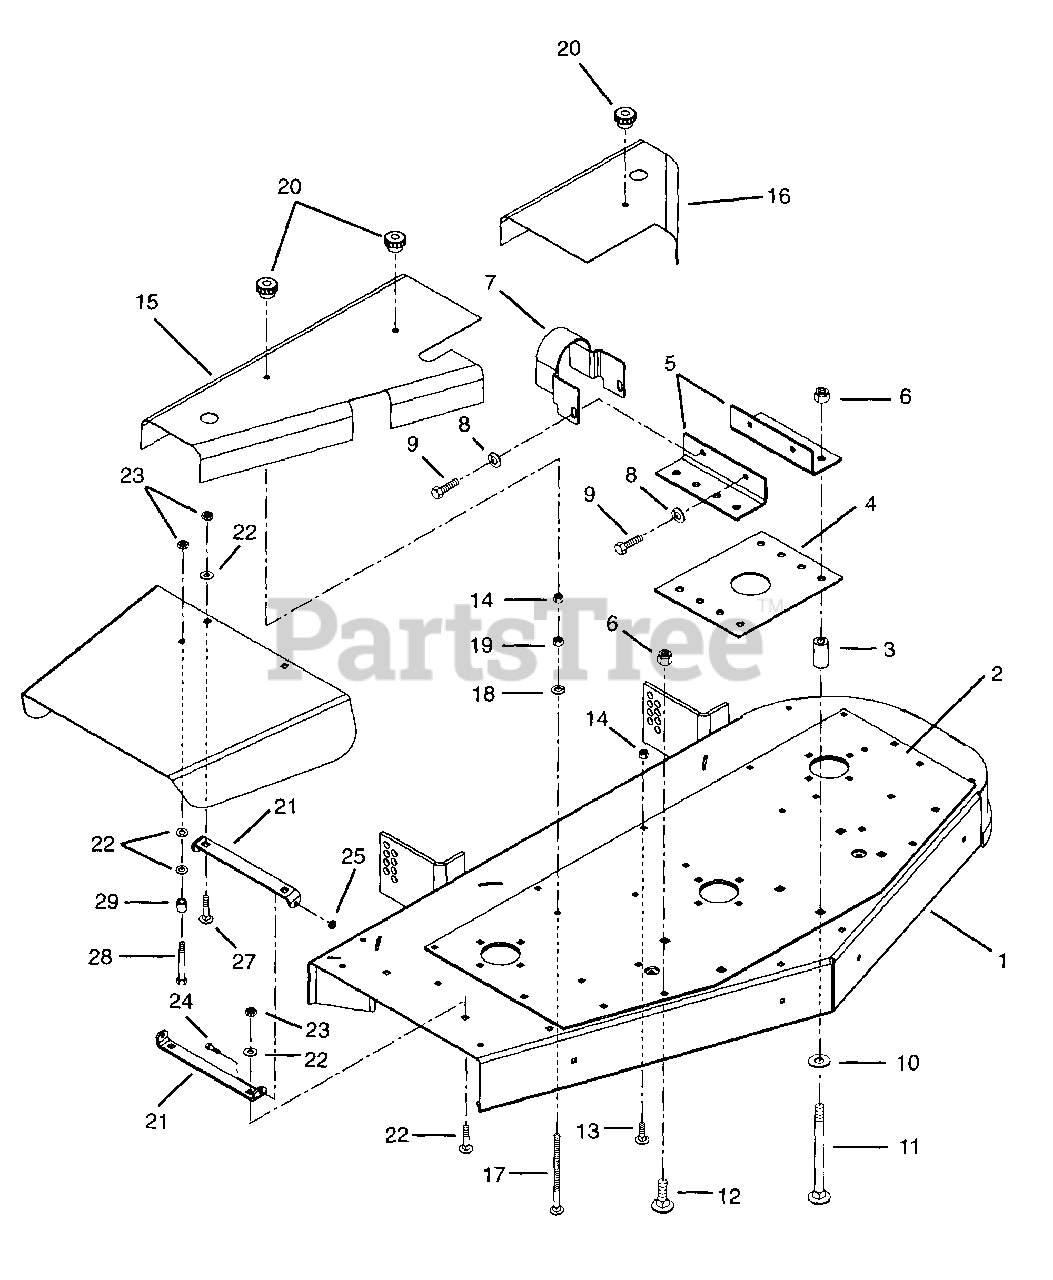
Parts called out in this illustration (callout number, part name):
1	Weldment, 50" Mower Deck
2	Plate, 50" Deck Reinforcing
3	Spacer .562 x 1.00 x 2.00
4	Plate, Gearbox Support
5	Bracket, Gearbox
6	Nut-Locking-Nylon .50-13 Grade 5
7	Shield, U-Joint
8	Washer-Lock .375 x .094
9	Bolt-Hex .380-16 x .875
10	Washer-Flat-Steel .531 x 1.062 x .095
11	Bolt-Hex .50-13 x 3.75
12	Bolt-Round Head Square Neck .50-13 x 1.00
13	Bolt-Round Head Square Neck .31-18 x .62
14	Nut-Locking-Nylon .312-18 Grade 2
15	Cover, Mower Belt Right Hand
16	Cover, Mower Belt Left Hand
17	Bolt-Round Head Square Neck.31-18 x 3.50
18	Washer-Lock .313 x .078
19	Nut-Hex .312-18 Grade 2
20	Knob
21	Bracket, Chute
22	Washer-Flat-Steel .406 x .812 x .065
23	Nut-Locking-Nylon .375-16 Grade 2
24	Bolt-Hex .25-20 x .875
25	Nut-Locking-Nylon .250-20 Grade 2
26	Shield, Safety External 50" Mower
27	Bolt-Round Head Square Neck .38-16 x 1.0
28	Bolt-Hex .38-16 x 1.50
29	Bushing-Sleeve .407 x .625 x .750
